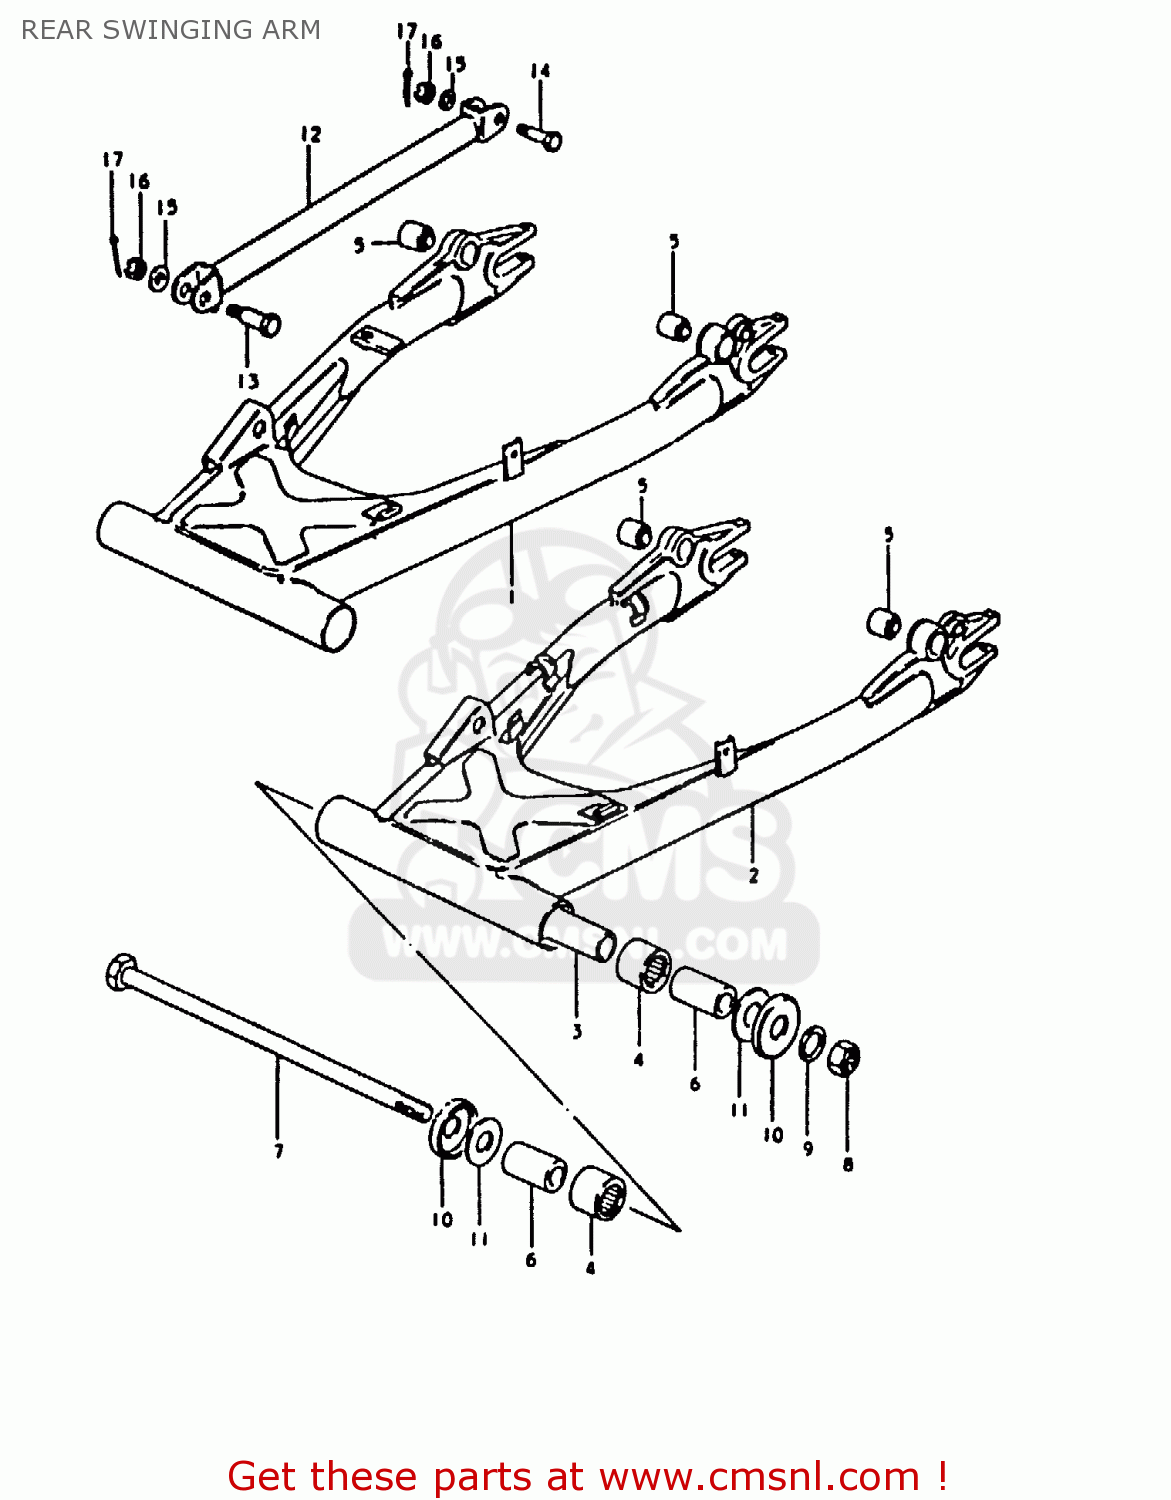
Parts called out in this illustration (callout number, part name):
1	SWING ARM ASSEMBLY,REAR
2	SWING ARM ASSEMBLY,REAR
3	BEARING(25X33X30)
4	BUSH
5	SPACER,RR SWGARM PIVOT CTR
6	SHAFT,REAR SWING ARM
7	NUT 16MM
8	WASHER
9	SPACER,RR SWGARM PIVOT
10	COVER,RR SWGARM DUST SEAL
11	WASHER
12	LINK,REAR TORQUE
13	BOLT
14	BOLT(10X39)
15	WASHER
16	NUT
17	PIN 20X20
